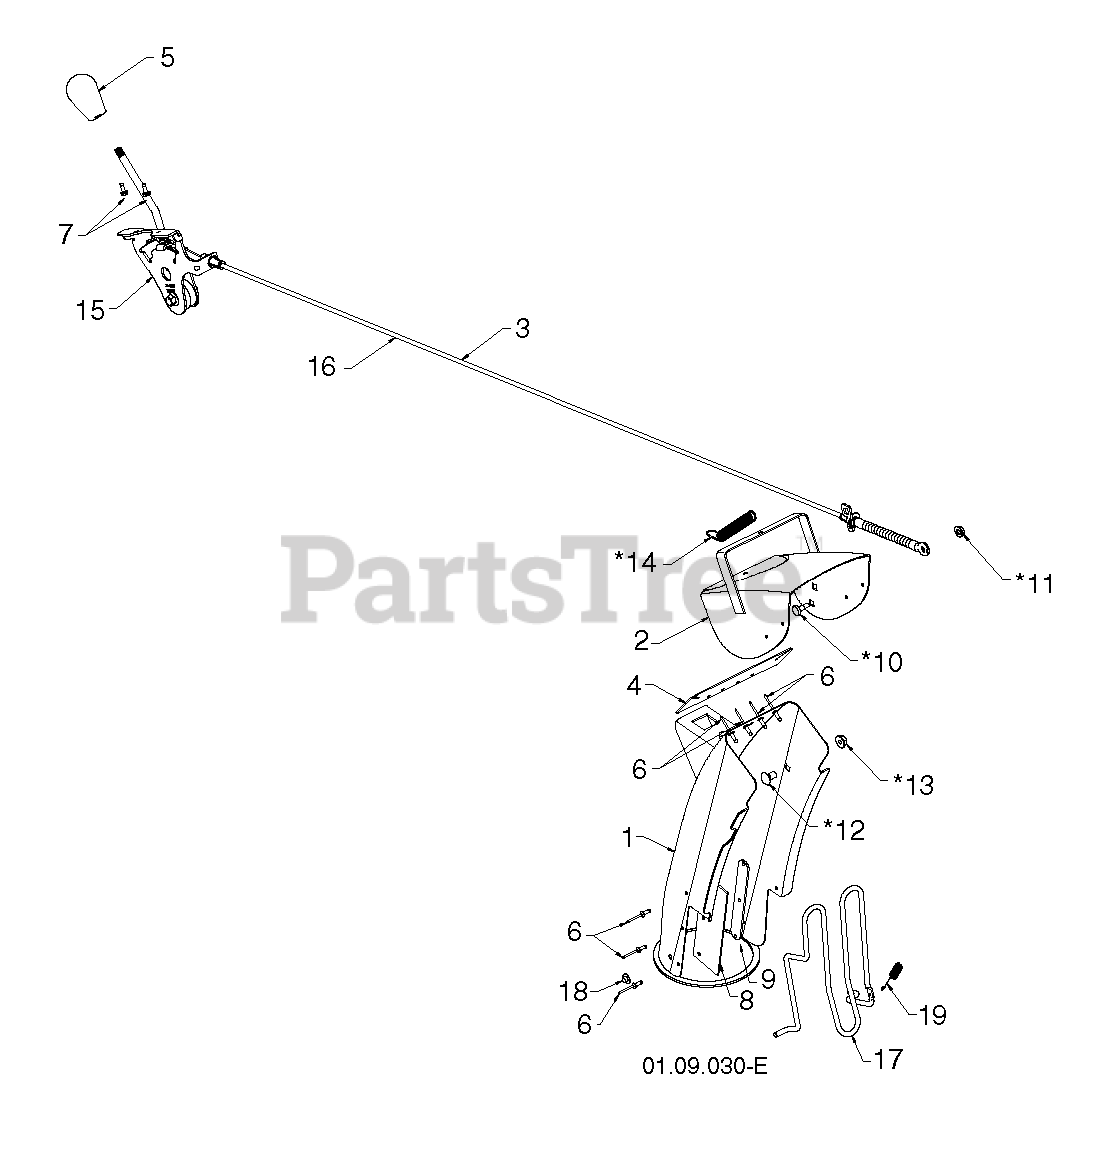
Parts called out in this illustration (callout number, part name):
1	CHUTE.WELDMENT.SNOW.ORANGE
2	DEFLECTOR.WELDMENT.PNT.ORANGE
3	CONTROL.ASM.DEFLEC.BLK.BOWDEN
4	SEAL.DEFLECTOR
5	KNOB.OVERMOLD.DS.HUSQVARNA/BLK
6	RIVET BLIND
8	SHIELD.SNOW.CHUTE
9	STRAP.SHEILD.RETAINER
15	RP CNTRL.HEAD.ASSEM.DEFLECTOR
16	RP CABLE.DEFLECTOR.BOWDEN
17	ROD.GUARD.CHUTE (2 2)
18	NUT
19	SPRING.CHUTE.GUARD
